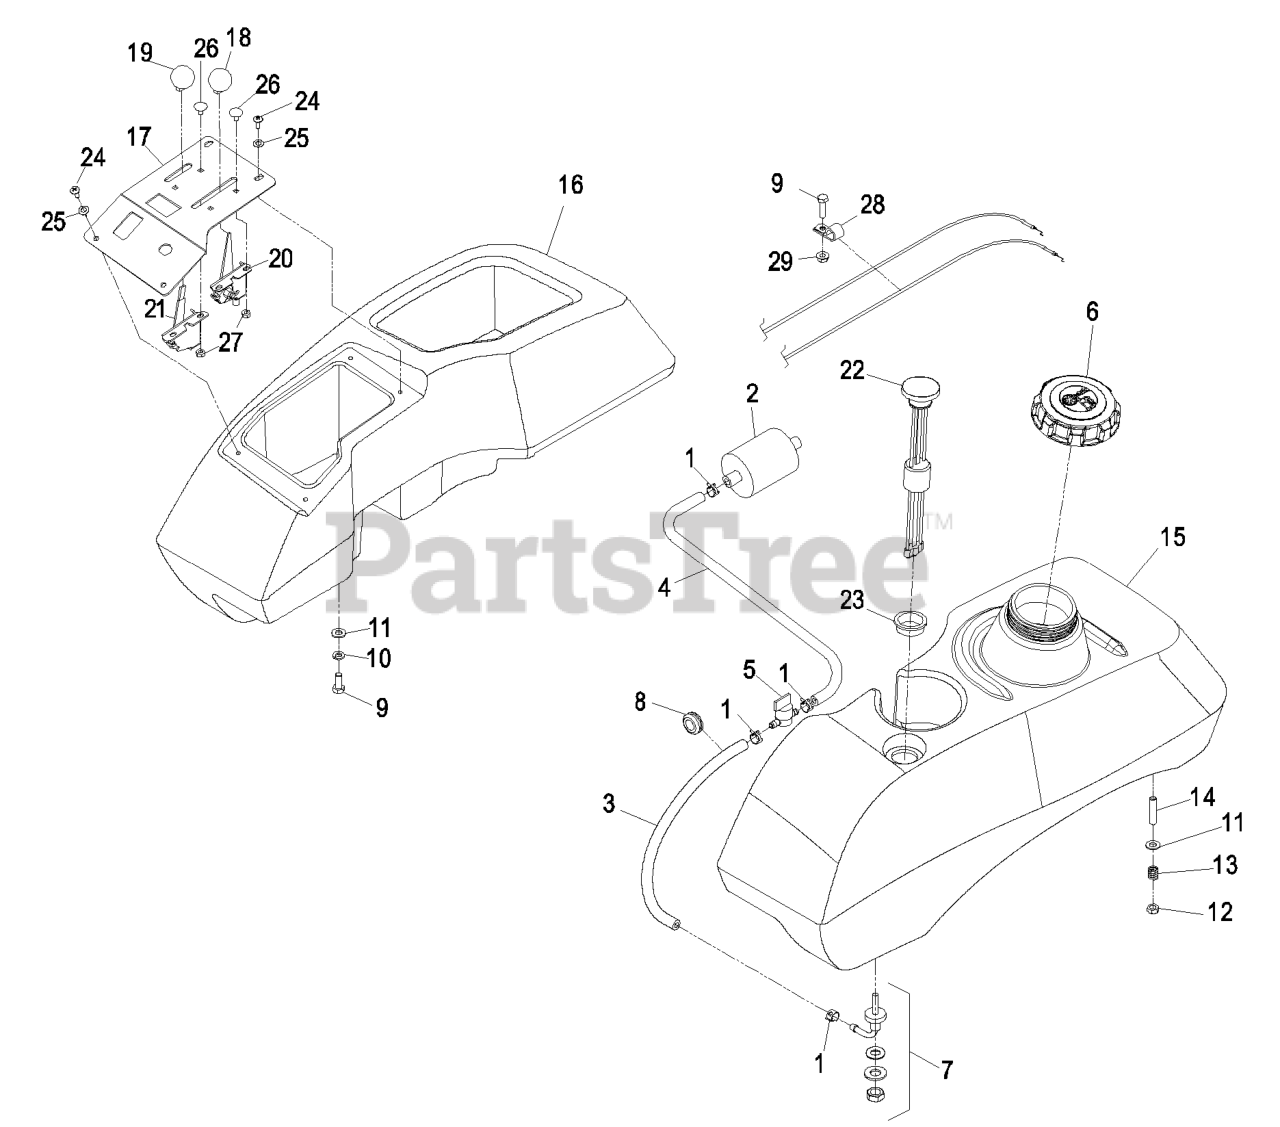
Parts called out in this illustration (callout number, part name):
2	Kohler Part No. 2405002 Fuel Filter
3	FUEL LINE,19.0
4	HOSE-FUEL
5	VALVE-FUEL
7	FITTING-FUEL, BULKHEAD
8	GROMMET
9	SCREW-HH
10	WASHER-LOCK
11	WASHER-PLAIN
12	NUT-LOCK, NI
13	SPRING-TANK, FUEL
14	STUD
15	KIT,FUEL TANK LH LCT
16	KIT,TANK RH LCT
18	KNOB-BALL
19	KNOB-BALL, BLACK
20	CABLE,LEVER CONTROL
21	CABLE,LEVER CONTROL
23	CONTACT ORDER SERVICES
24	SCREW-PTH
25	WASHER-SPRING
26	BOLT-CARR
27	NUT-LOCK, NI
28	CLIP-LOOM
